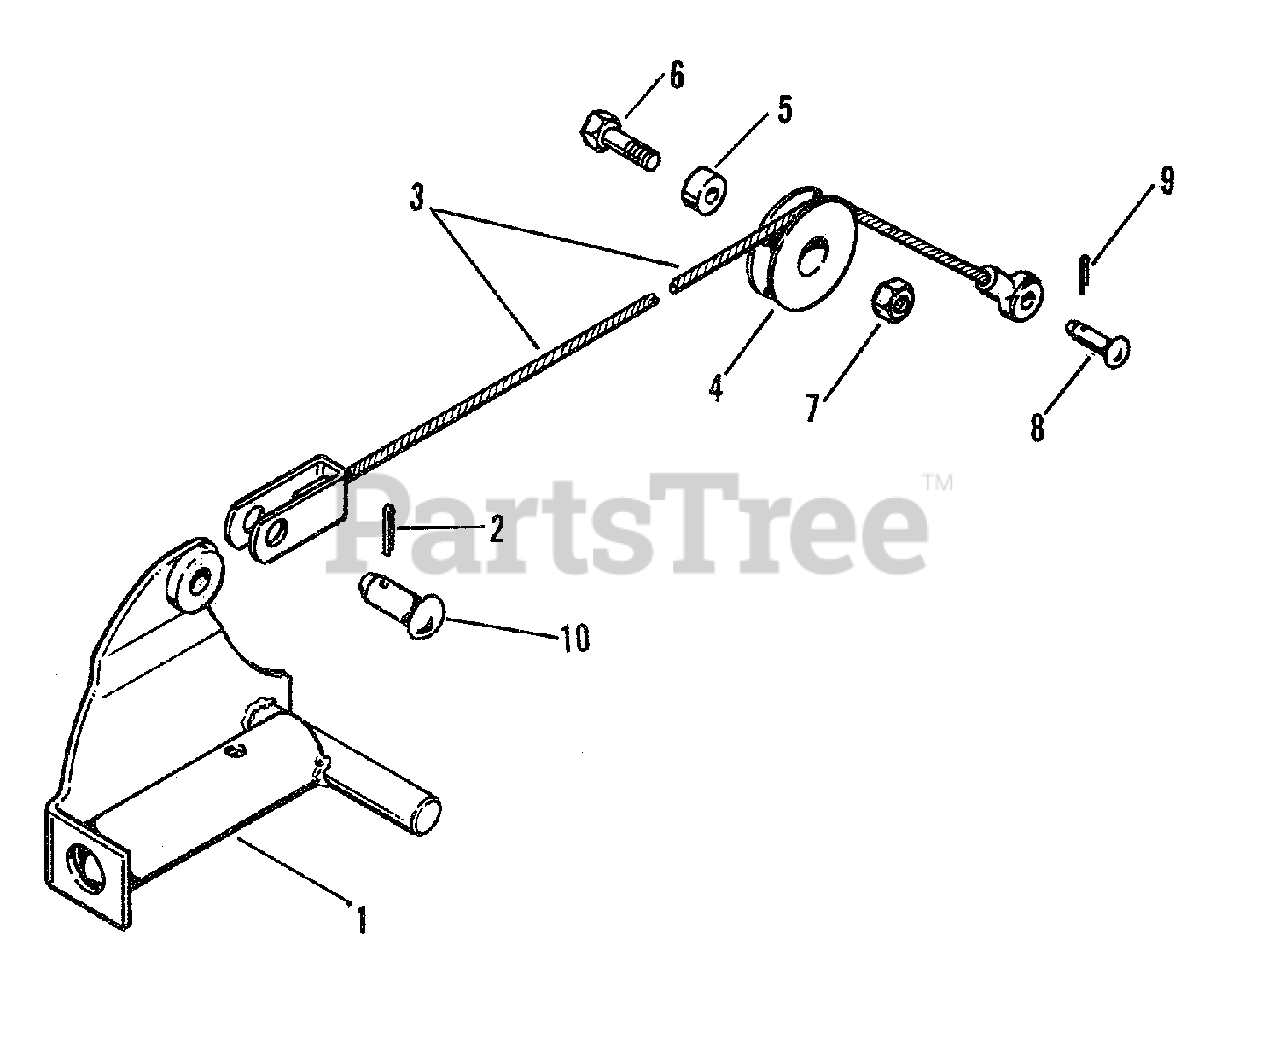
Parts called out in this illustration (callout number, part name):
1	LIFT LEVER ASSEMBLY
2	PIN
3	LIFT CABLE ASSEMBLY
6	HEX CAPSCREW, 3/8"-16 x 1-1/4" Lg.
7	HEX JAM NUT, 3/8"-16
8	COTTER PIN, 1/8 x 1" Lg.
10	COTTER PIN, 3/32 x 7/8" Lg
